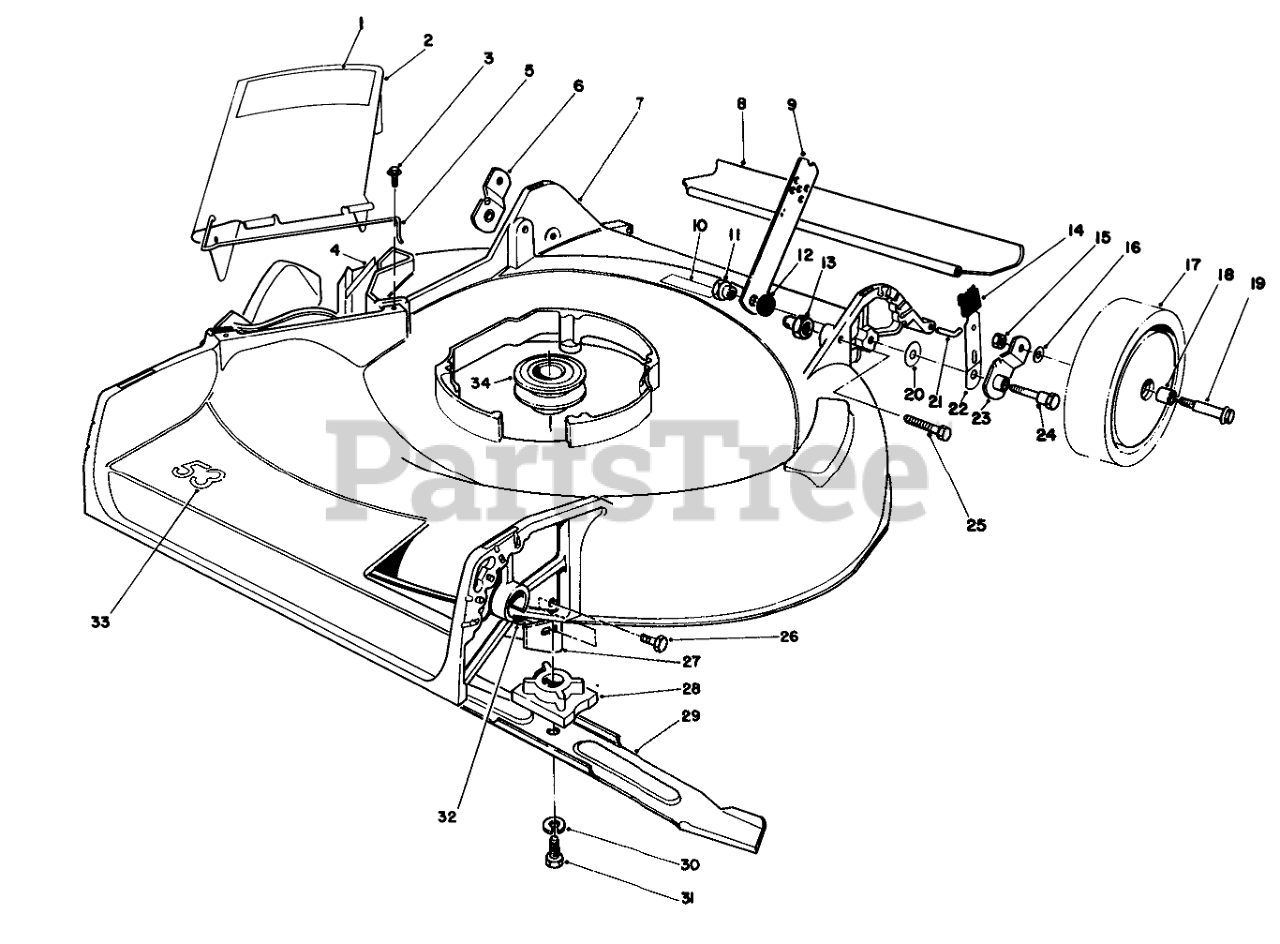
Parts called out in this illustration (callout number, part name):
1	DECAL - DANGER DEFL
2	Deflector (Incl. Ref. #1)
3	SCREW-HWH
4	DANGER DECAL
5	SPRING HINGE
6	Pivot Arm
7	HOUSING/DECAL
8	REAR SAFETY SHIELD 21
9	HANDLE LATCH
10	Decal
11	HANDLE PIVOT NUT
12	SPACER
13	HANDLE PIVOT NUT
14	KNOB-ARM
15	Nut
16	WASHER
17	Wheel 8 Tire Assembly (Incl. Ref. #18)
18	BUSHING
19	BOLT-WHEEL
20	WASHER-PIVOT
21	SHIELD ROD
22	SPRING ARM ASM
23	Pivot Arm
24	PIVOT SCREW
25	SCREW-HH
26	SCREW-HH
27	Shield Front
28	BLADE RETAINER
29	Blade
30	WASHER-LOCK
31	SCREW-HH
32	NUT-LOCK, NI
33	DECAL - 53
34	PULLEY-DRIVER
